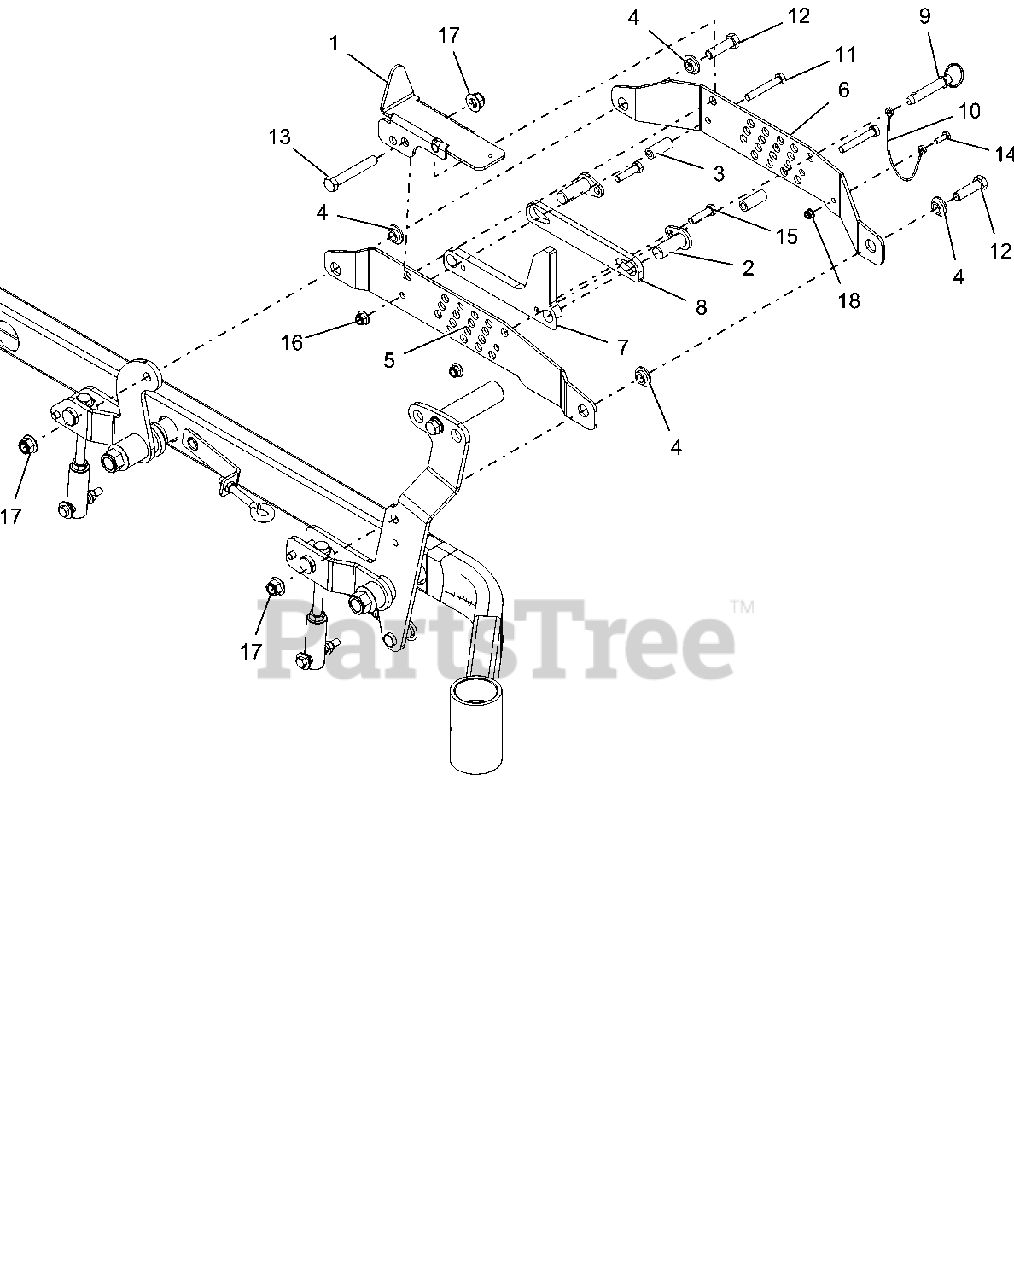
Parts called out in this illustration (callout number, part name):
1	WLDMT, MECHANICAL LOCK-UP-BLACK
2	WLDMT, PIN
3	SPACER, .375 X .625 X 1.54
4	BSHG, FLANGE .515X.750X.31X1.12
5	BRKT, RH INBOARD LIFT/CUT HEIGHT-BLACK
6	BRKT, RH INBOARD LIFT/CUT HEIGHT-BLACK
7	BRKT, HOC STOP-BLACK
8	BRKT, HOC STOP-BLACK
9	PIN, .500 x 2.000 USABLE LG BALL
10	LANYARD, 12"
11	BLT-HEX .38-16X2.50 GR5 YWZC
12	BLT-HEX .50-13X1.75 GR5 YWZC
13	BLT-HEX .50-13X3.25 GR5 YWZC
14	BLT-HEX .25-20X.75 GR5 YWZC
15	BLT-HEX .38-16X1.50 GR5 YWZC EP30
16	NUT-LK-NYL-FLG .38-16 YWZC
17	NUT-LK-NYL-FLG .50-13 YWZC
18	NUT-LK-NYL-FLG .25-20 YWZC
